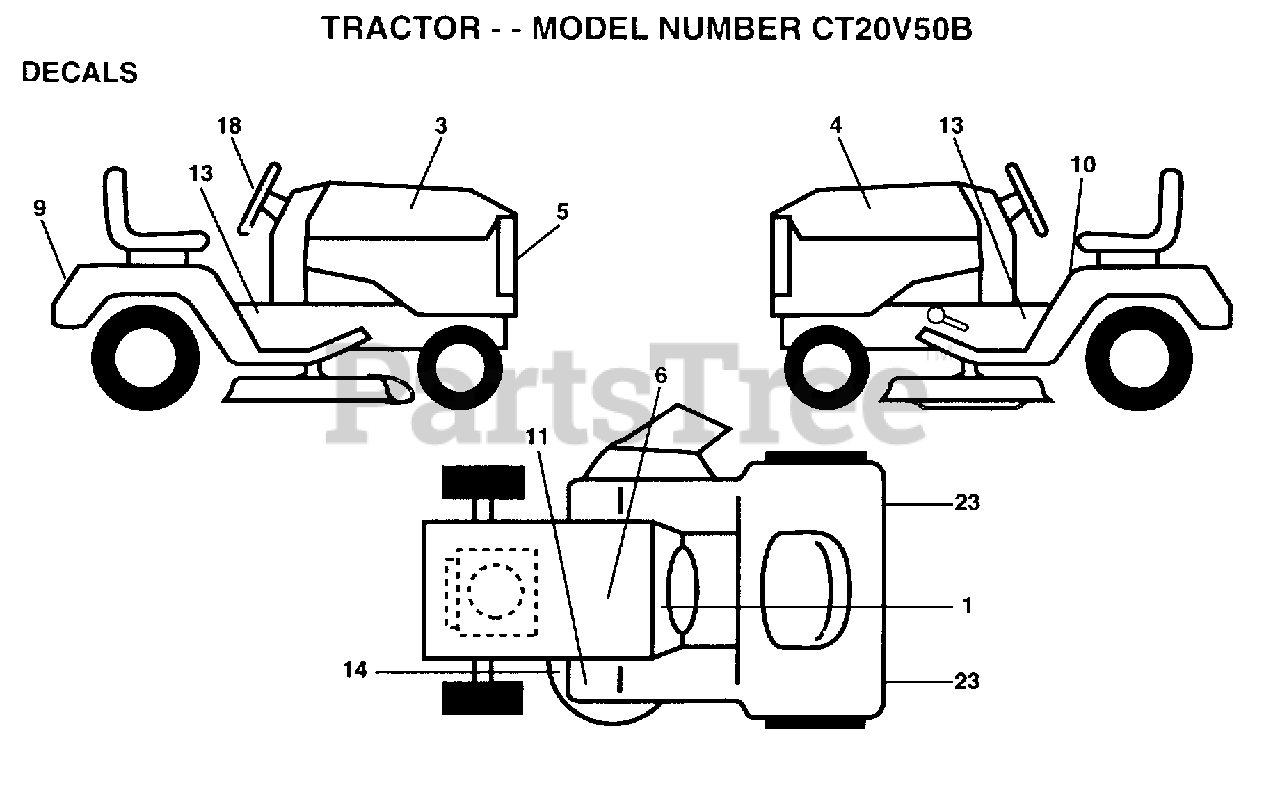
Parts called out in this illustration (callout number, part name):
1	DECAL.DASH.INST.
3	DECAL.HD.RH.RALLY
4	DECAL.HD.LH.RALLY
5	DECAL.GRILLE.RLY
6	DECAL.BTRY.DANGER
9	DECAL.FEND.RALLY
10	DECAL
13	DECAL.CHAS.6.RALL
14	"DECAL.V.BELT.44"""
18	DECAL.WHL.STR.RLY
23	REFLECTOR-TAIL YT
